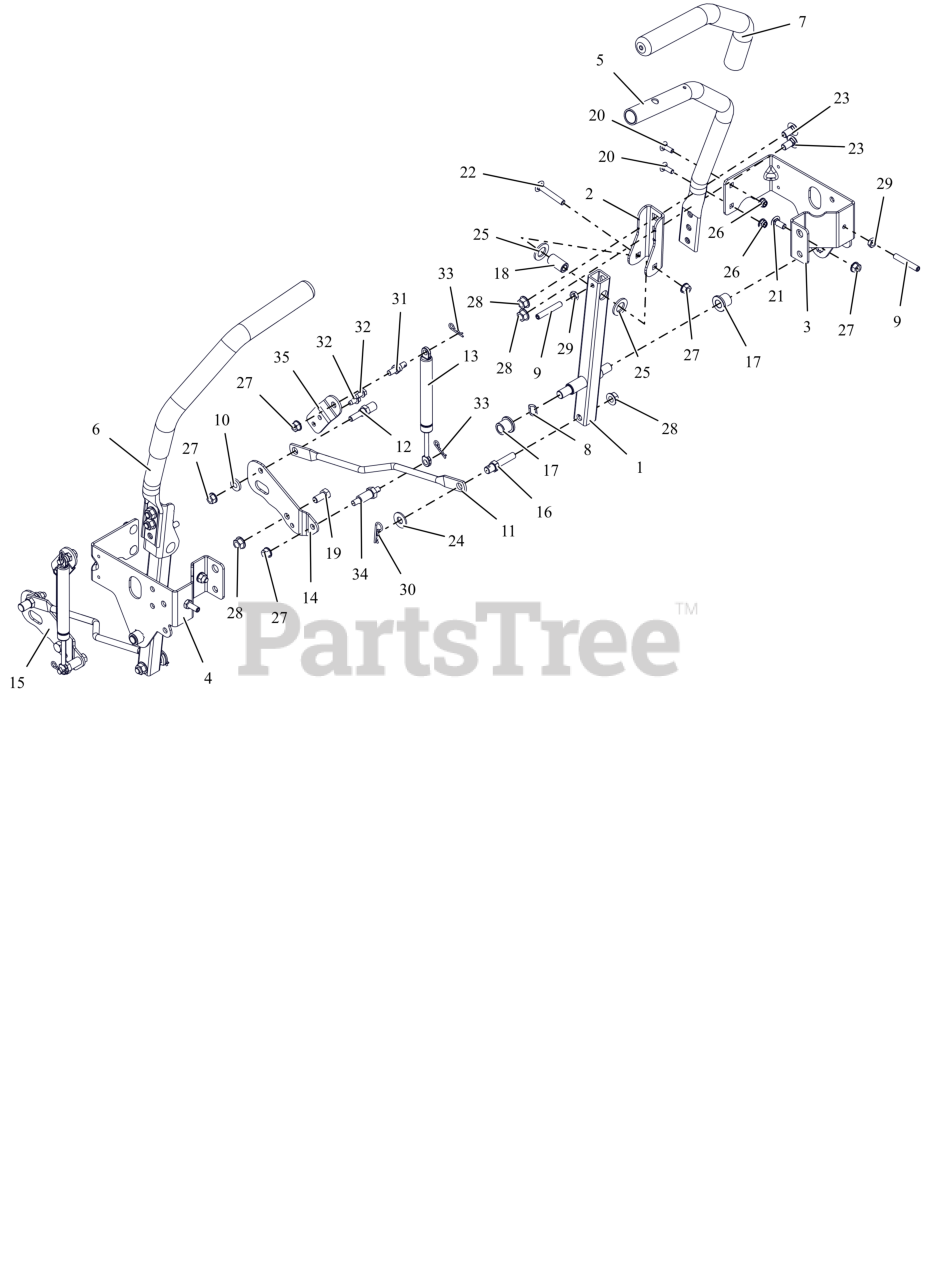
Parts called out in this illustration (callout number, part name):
1	WLDMT, LOWER CONTROL ARM (BLACK)
2	ARM, CONTROL -UPPER (BLACK)
3	BRKT, SPEED ADJ/SEAT PIVOT-LH (BLACK)
4	BRKT, SPEED ADJ/SEAT PIVOT-RH (BLACK)
5	WLDMT, CONTROL HANDLE -LH (BLACK)
6	WLDMT, CONTROL HANDLE - RH (BLACK)
7	GRIP, HANDLEBAR 15" FOAM
8	WAVE WASHER .531X.781X.125FH
9	SCR-SET, .312-18X2.000 SS
10	BSHG-FLG .316X.430X.225X.750
11	LINKAGE, STEERING
12	STUD, STEERING LINK-REAR
13	DAMPER, STRAIGHT MOUNT
14	PLATE, DAMPER RH
15	PLATE, DAMPER
16	STUD, STEERING LINK -FRONT
17	BHSG-FLG .500X.750X.750X.125
18	BSHG, -SLV .342 X .627 X 1.171
19	BLT,HEX .38-16X.75 G5 ZCC
20	BLT, RHSN .25-20X.750 G5 ZCC
21	BLT, RHSSN.31-18X.750 G5 ZCC
22	BLT, RHSSN .31-18X2.00 G5 ZCC
23	BTL,RHSSN .375-16 X 0.75 G5 FPB
24	WSHR,FLT .438X1.00X.083 ZCC
25	WSHR, FRICTION
26	NUT,NYL-FLG .25-20 GF ZCC
27	NUT,LK-CTR-FLG .31-18 GF ZCC
28	NUT-LK-CTR-FLG .375-16 GF ZCC
29	NUT-JAM .312-18 G2 ZCC
30	PIN, HAIR .09 X 1.50 ZCC
31	COUPLER, DAMPER MOUNT
32	SCR-TAP .25-20X.50 HWH ZCC
33	PIN, HAIR #213 .08X1.19 ZCC
34	COUPLER, DAMPER MOUNT (LOWER)
35	PLATE, DAMPER TOP MOUNTING (BLACK)
